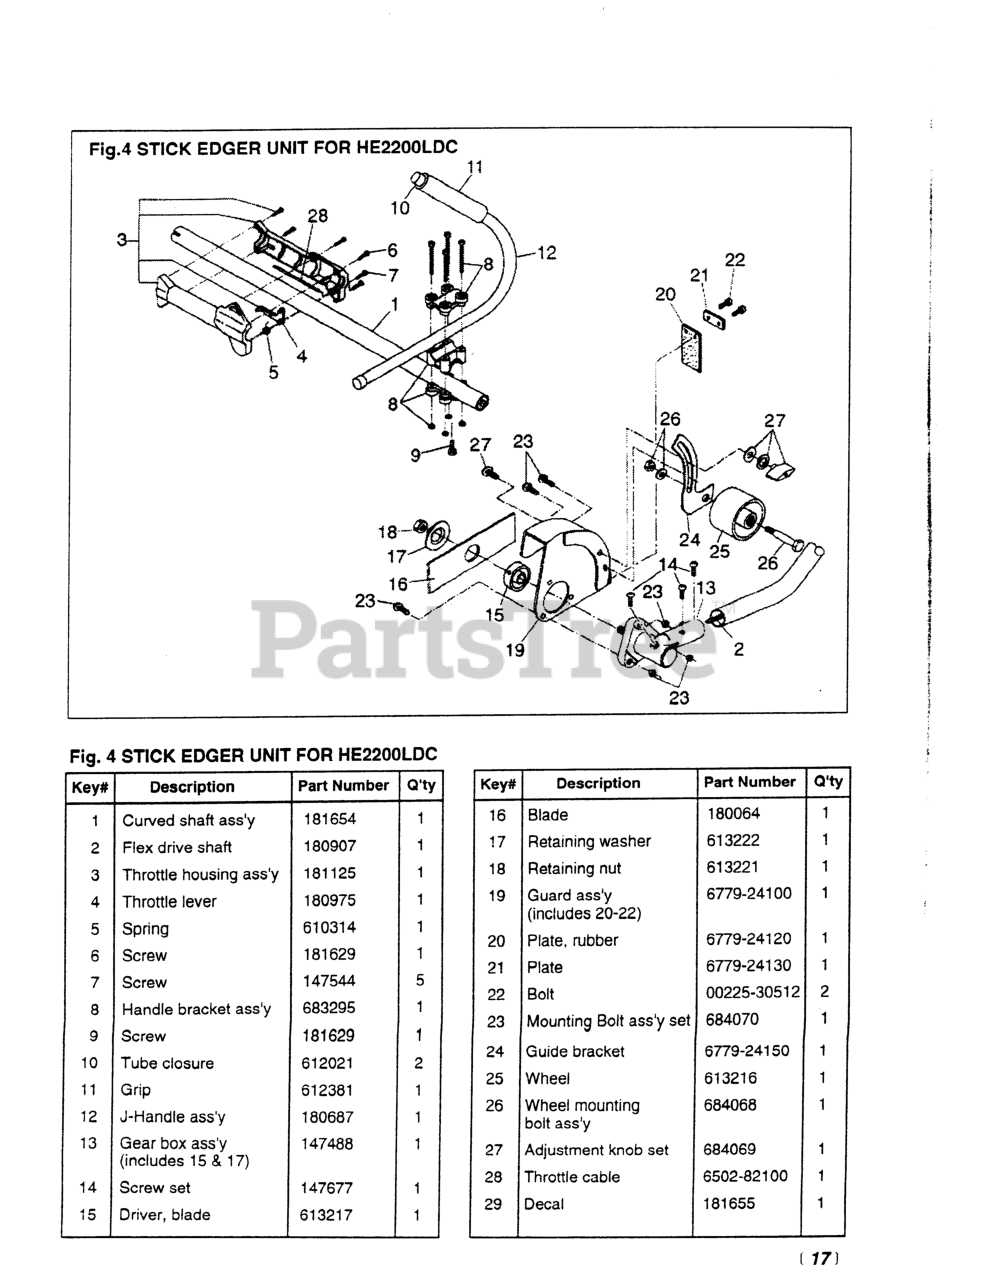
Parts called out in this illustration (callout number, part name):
1	ASSY, DRIVE SHAFT HOUSING (CS)
2	SHAFT, FLEX (RLPS. 181773)
4	LEVER, THROTTLE
5	SPRING, THROTTLE TRIGGER
6	SCREW, 8-32 X .437
8	HANDLE BRACKET ASSEMBLY
9	SCREW, 8-32 X .437
10	CAP
13	GEARCASE ASSEMBLY
14	HARDWARE, MOUNTING
18	NUT, RETAINING
19	GUARD ASSEMBLY
20	PLATE, RUBBER
23	MOUNTING BOLT ASSY SET
26	WHEEL MOUNTING BOLT ASSY
27	ADJUSTMENT KNOB ASSY
28	CABLE COMP (RPLS 6460- )
NI	LABEL, HE2200LDC
